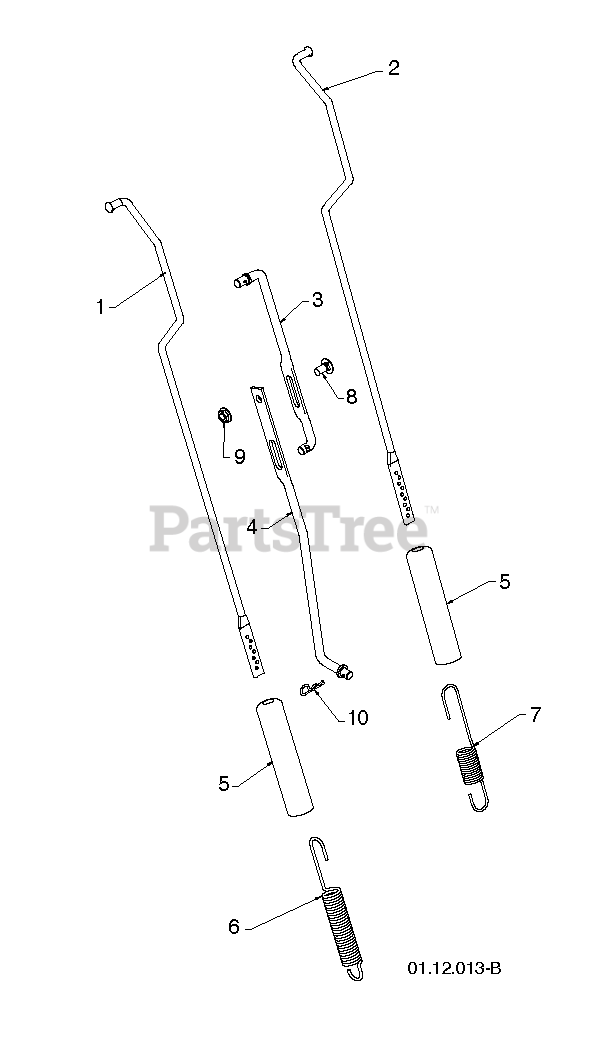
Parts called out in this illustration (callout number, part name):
1	ROD.IMPELLER
2	ROD.TRACTION
3	ROD, UPPER SPEED CONTROL
4	ROD, LOWER SPEED CONTROL.SNOW
5	SLEEVE, SPRING
6	SPRING.CONTROL.ROD.SNOW
7	SPRING.TRACTION.ROD.SNOW
8	BOLT
9	NUT.FLANGE.5/16
10	SPRING RETAINER
